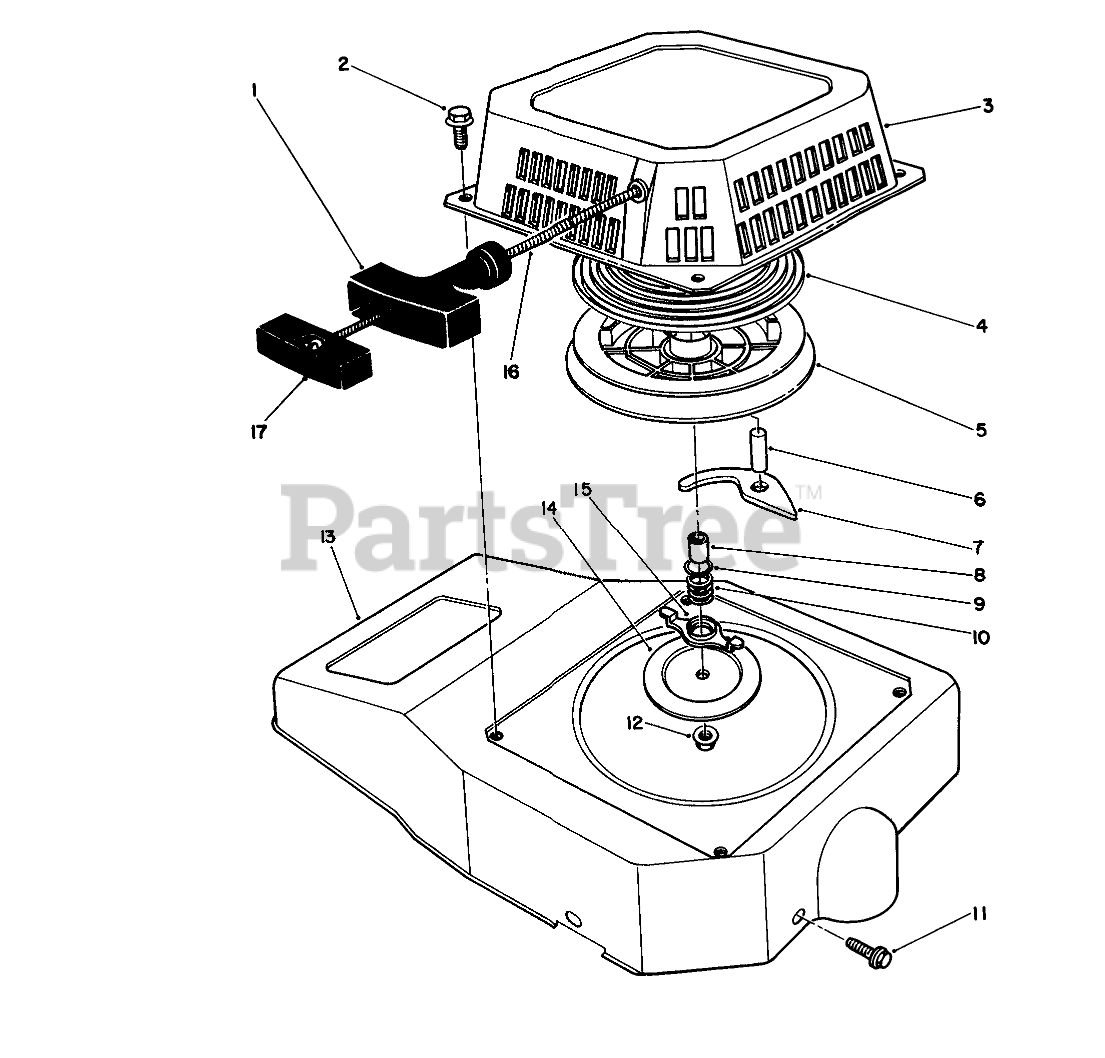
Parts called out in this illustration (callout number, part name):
1	HANDLE
2	SCREW-HHF
3	Case-Recoil
4	SPRING
8	Spacer
9	WASHER
10	Spring-Friction
13	SHROUD
14	PLATE
15	Guide-Paw
16	ROPE-STARTER
17	RETAINER HANDLE
